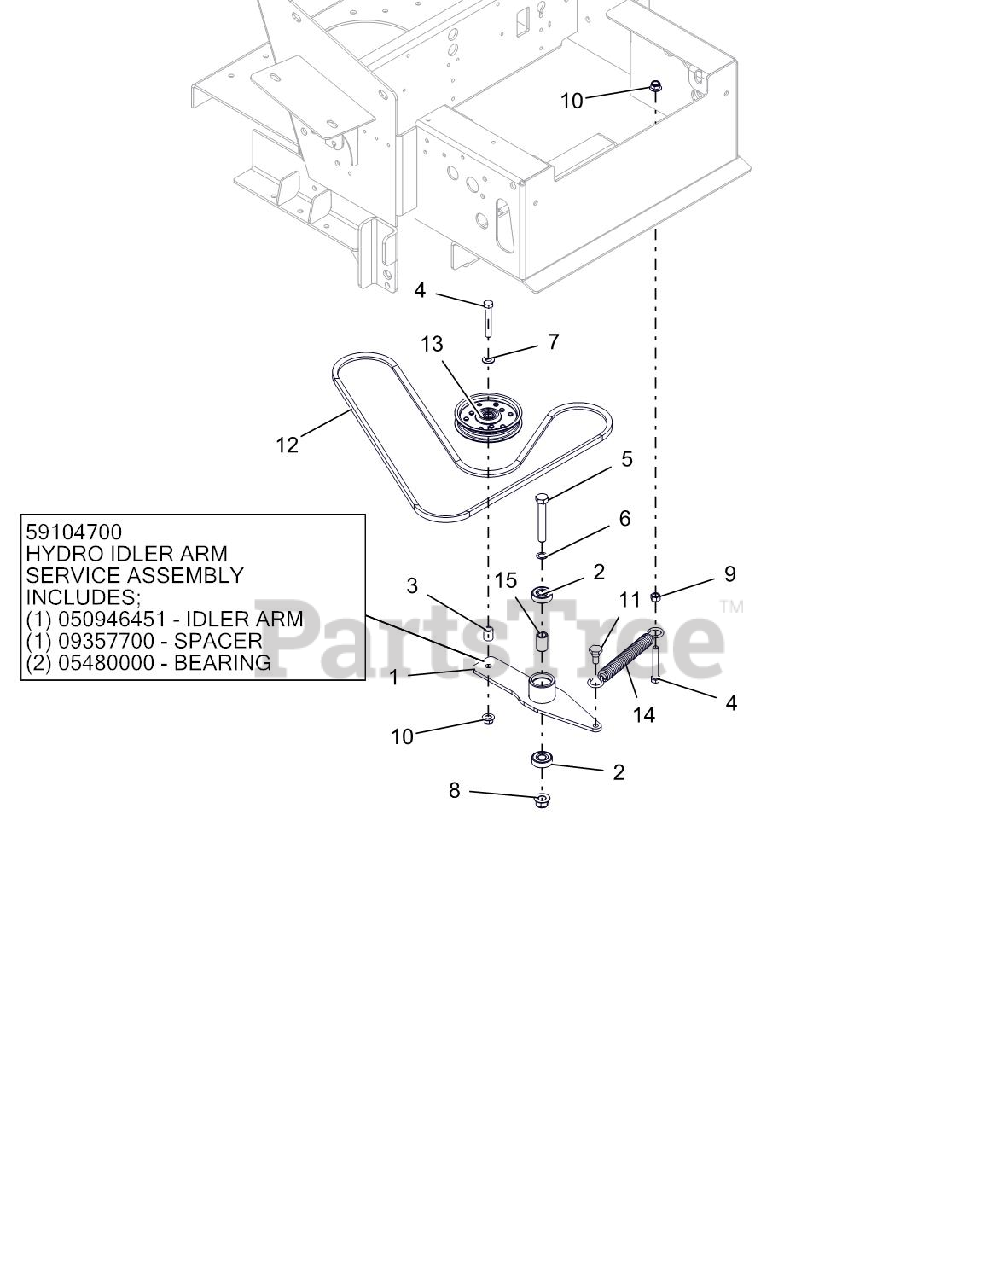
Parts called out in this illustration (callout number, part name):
1	BRG-BALL .50X1.38X.438 SEALED
1	SPACER .510 X .75 X 1.1485
1	HYDRO IDLER ARM ASSEMBLY
1	HYDRO DRIVE IDLER ARM WMT-BLK
2	BRG-BALL .500X1.38X.437
3	BSHG-SLV .407X.625X.750 PL
4	@BLT-HEX .38-16X2.50 GR5 YWZC
5	@BLT-HEX .50-13X3.25 GR5 YWZC
6	WASHER, .500X.750X.020 THRUST
7	@WSHR-FL-STL.406X.812X.065 YWZ
8	@NUT-LK-NYL-FLG .50-13 YWZC
9	@NUT-HEX .38-16 YWZC
10	@NUT-LK-NYL-FLG .38-16 YWZC
11	BLT,SHLDR EP .38-16X.30 HEX YZ
12	V-BELT, A-COGGED
13	ASM, 4" IDLER (.75 WIDE)
14	SPRING, EXTENSION
15	SPACER .510 X .75 X 1.1485
